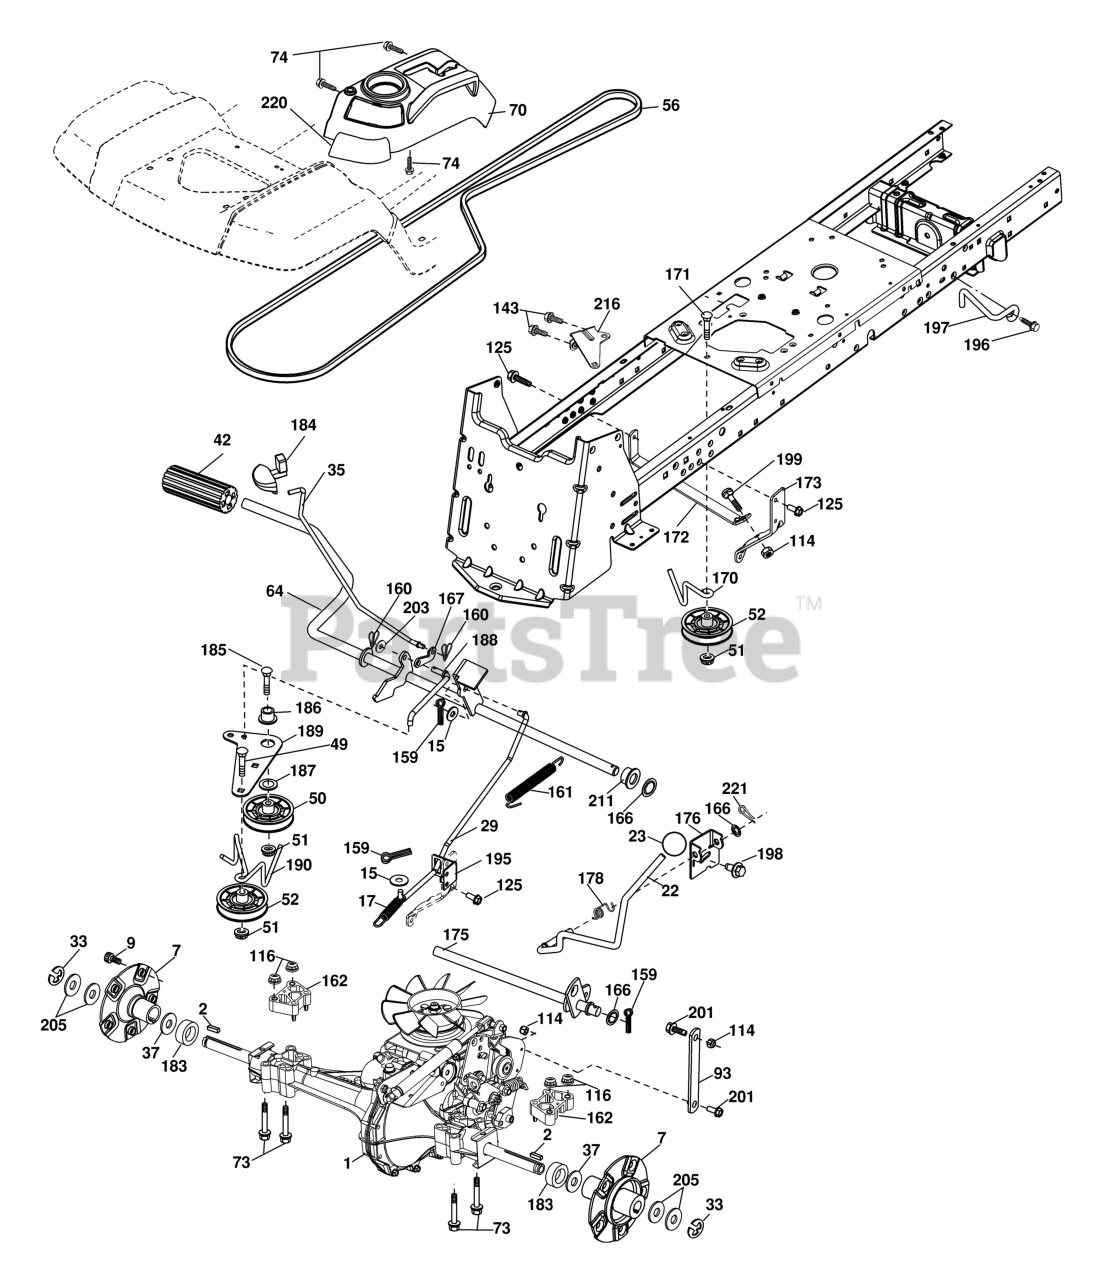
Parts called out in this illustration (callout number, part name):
2	KEY.SQUARE.187X2.500
7	HUB.ASM.WHEEL.REAR.22"
9	HUB BOLT
15	WASHER
17	SPRING.BRAKE.HG3000/3500
22	ROD.SHIFT.FENDER.STGT.
23	KNOB.DELUXE.(PISTOL.GRIP).BLAC
29	ROD.BRAKE.0610.PEDAL.CONTROL
35	ROD.BRAKE.PARKING.GT.H
42	PEDAL COVER T
49	BOLT
50	IDLER.FLAT.910.OFFSET
51	NUT LOCK FLG 3/8-16 UNC
52	IDLER.V-GROOVE.910.OFFSET
64	SHAFT.ASM.PEDAL.BRAKE.
70	RP CONSOLE.ASM.HYDO.HUSQ.
73	BOLT.HEX.FLNG.5/16-18X3.75
74	SCREW.HI-LO.CONSOLE
93	LINK.SHIFT.T/A.0610.TE
114	NUT.71038.31-18.HEX.NYLOCK
116	NUT LOCK HEX FLANGE 5/16-18
125	SCREW
143	Screw Thdrol 5/16-18 x 1/2
159	COTTER PIN
160	RETAINER CLIP
161	SPRING.RETURN.CLUTCH.2006
162	SPACER.TRANSAXLE.18&22
166	NUT.PUSH.625.2006
167	LATCH.BRAKE.SPRING
170	KEEPER.V-IDLER.CENTER.
171	BOLT
172	STRAP.TRQ.LH.FS.HG0510
173	STRAP.TORQUE.FS.0610.RH
175	SHAFT.ASM.SHFT.HG0510/
176	ARM.CLEVIS.ROD.SHIFT
178	SPRING.SHIFT.GT2006
183	SPACER.SPLIT.800X.350
184	HANDLE.PARKG.BRK.HUSQ X667
185	BOLT
186	SPACER.RETAINER
187	WASHER 12/32X2X10GA
188	RP.LINK.CLUTCH.GROUND.DRIVE
189	BELLCRANK.GROUND.DRIVE.TEX.
190	KEEPER.BELLCRANK.DRIVE
195	BRKT.ROD.BRAKE.18/20/2
196	SCREW 3/8-16X1
197	BRKT.ANIT-ROTATION.CLUTCH
198	SCREW.7/16-14X7/8.FLAN
199	BOLT
201	BOLT SHOULDER 5/16-18 UNC
203	WASHER
211	BUSHING.SHAFT.BRAKE.HAND
216	BRACKET.PULLEY.IDLER.W/TEX
220	REFLECTOR.RH.TEX GT
221	RETAINER.SPRING.CLIP.H
